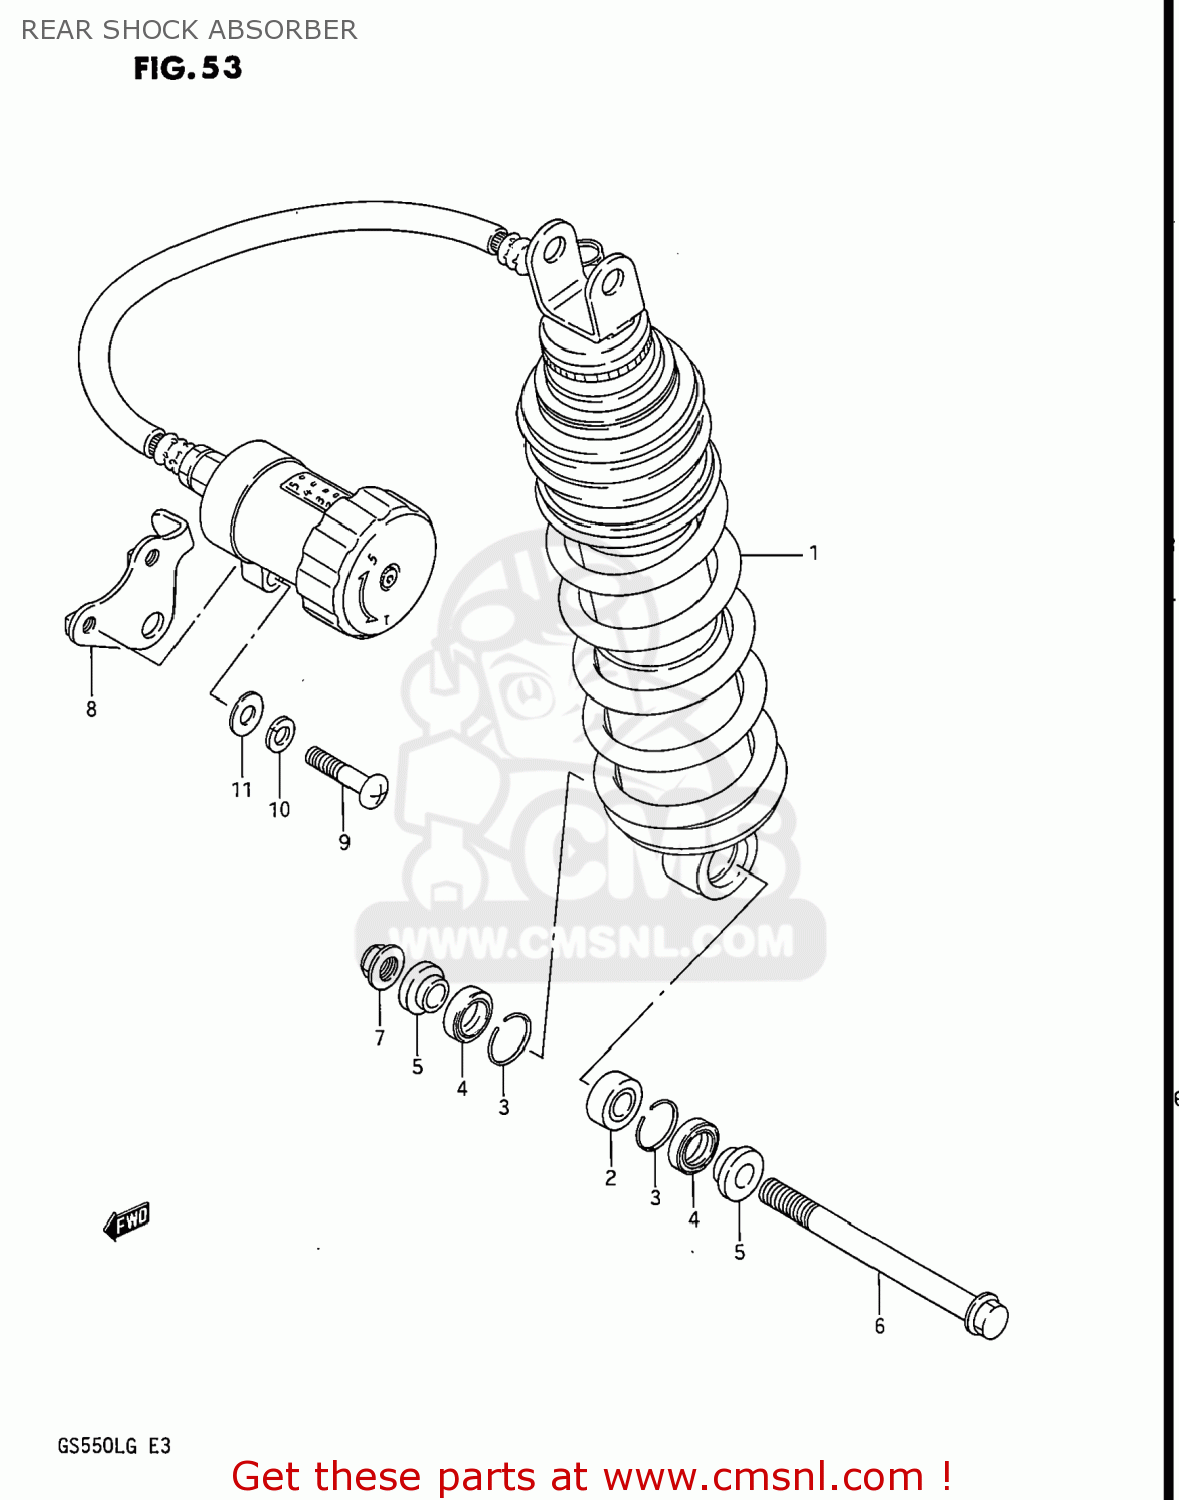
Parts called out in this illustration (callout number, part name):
1	ABSORBER ASSEMBLY,REAR SHOCK
2	BEARING,REAR SHOCK ABSORBER
3	RING
4	DUST SEAL
5	COLLAR
6	BOLT(10X115)
7	NUT
8	BRACKET,RESERVOIR TANK
9	SCREW
10	WASHER,LOCK
11	WASHER
